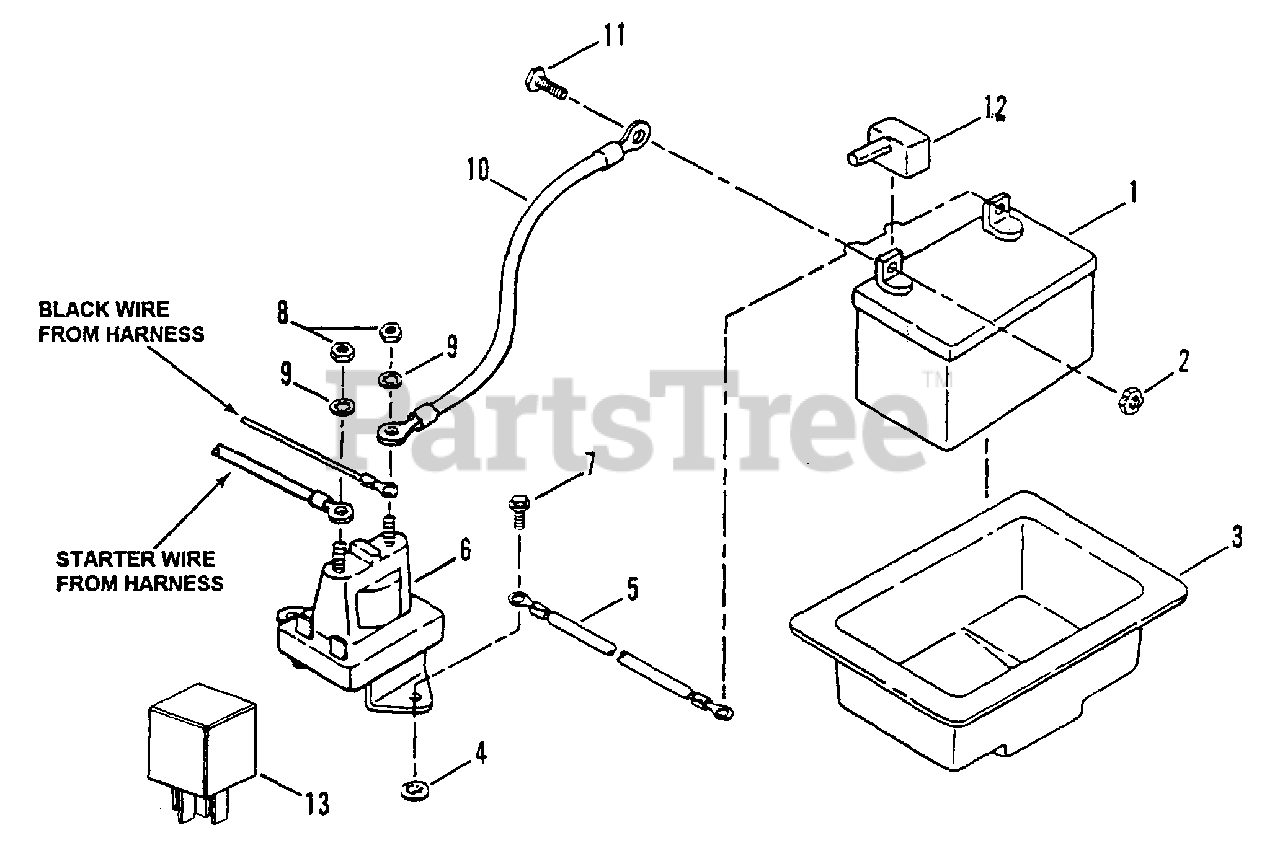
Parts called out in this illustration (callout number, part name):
1	KIT, Battery
2	NUT, 1/4-20 Hex Center Lock, Grade 5 or B
3	TRAY, Battery
4	RETAINER, Screw
5	CABLE, Ground (Black)
6	SOLENOID
7	SCREW, 1/4-20 x 1/2" Self-Tapping
8	NUT, 1/4-20 Hex Jam
9	WASHER, 1/4 Internal Tooth Lock
10	CABLE, Positive (Red)
11	SCREW, 1/4-20 x 5/8" Hex Head Cap, Grade 5
12	COVER, Positive Terminal
13	RELAY
